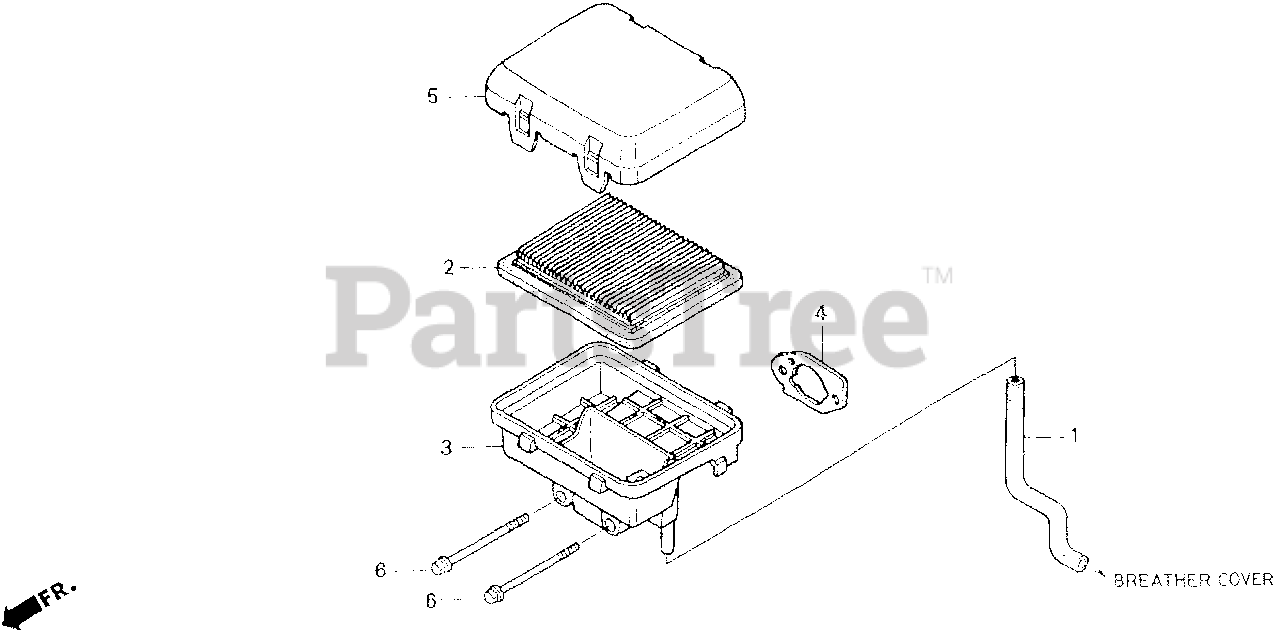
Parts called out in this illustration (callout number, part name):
1	TUBE, BREATHER
2	ELEMENT, AIR CLEANER
3	HOUSING, AIR CLEANER
4	GASKET, AIR CLEANER
5	COVER, AIR CLEANER
6	BOLT, FLANGE (6X112) (CT200)
